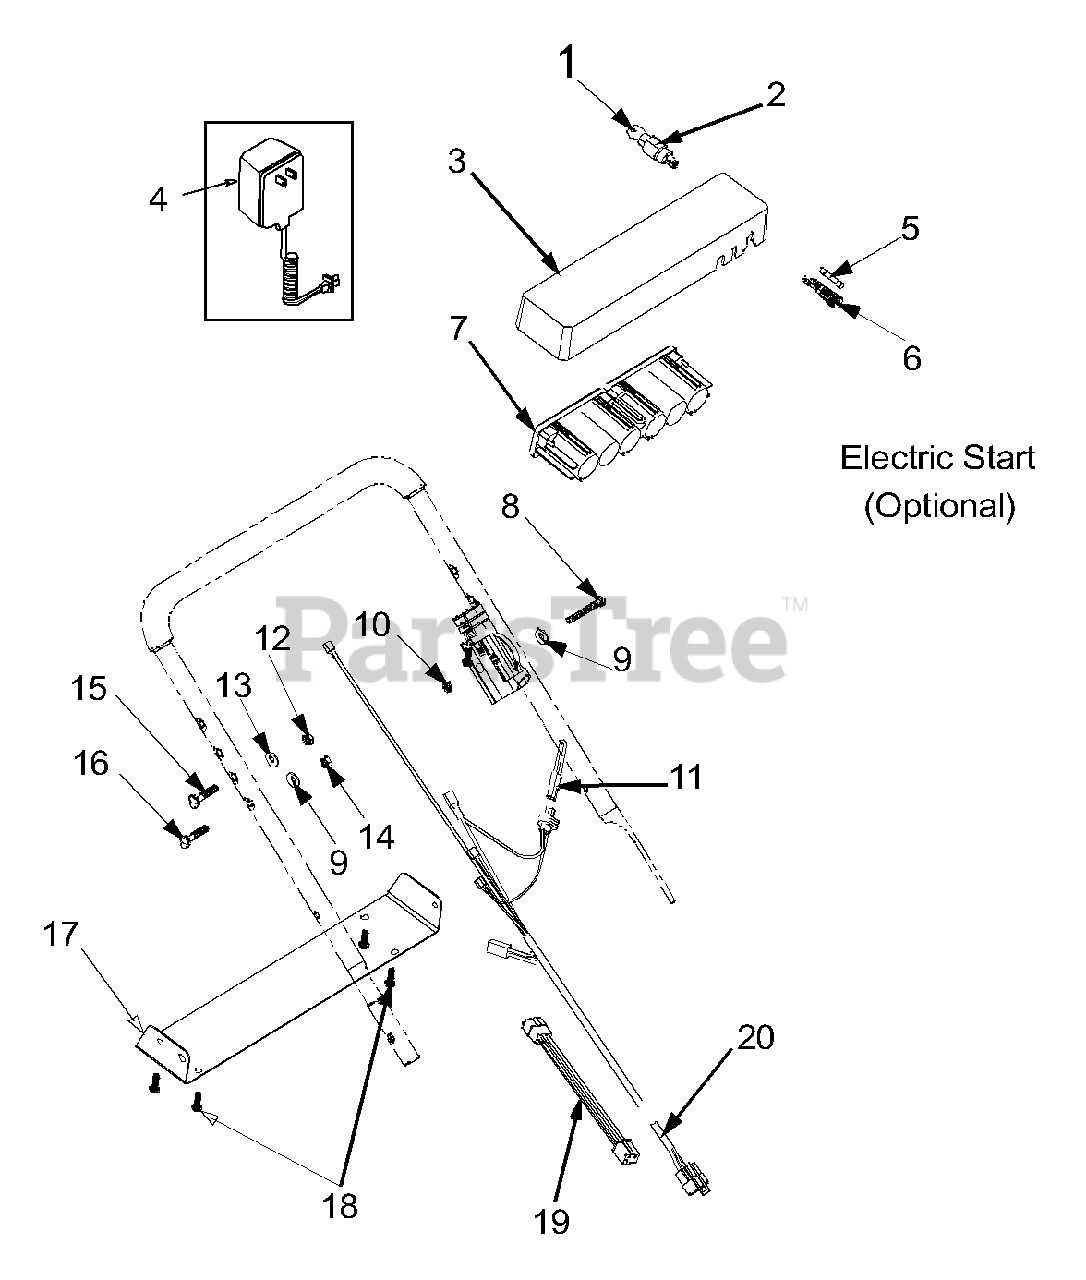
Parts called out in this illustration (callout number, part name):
1	Ignition Key
2	Key Switch
3	Battery Tray
4	Battery Charger
5	Fuse 7.5 Amp
6	Fuse Holder
7	Battery 12V
8	Hex Screw:1/4-20:2.0
9	Bell Washer .265 x .75 x .062
10	Special Hex Nut 5/16-18
11	Plug
12	Nut 5/16-18
13	Bell Wash .340 ID x .872 OD
14	Hex Nut 1/4-20
15	Carriage Bolt 5/16-18 x 1
16	Carriage Screw
19	Harness Extension
20	Harness
